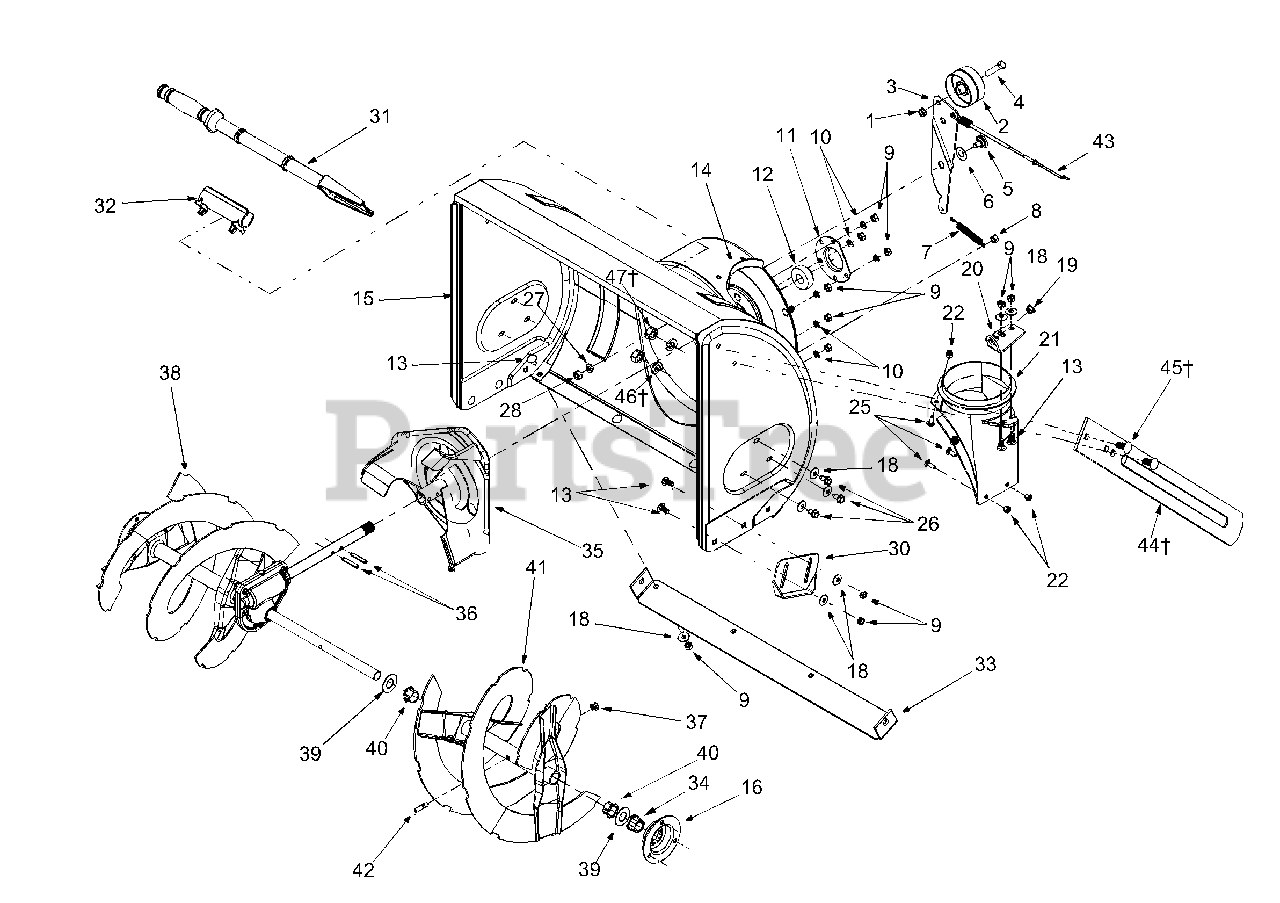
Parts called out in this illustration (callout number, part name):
1	Lock Jam Nut 3/8-24
2	Flat Idler
4	Hex Cap Screw 3/8-24 x 1.50
5	Shoulder Screw
6	Flat Washer,.565 x 1.25 x.02
7	Extension Spring
8	Hex Nut 5/16-18
9	Hex Nut 5/16-18
10	Lock Washer 5/16
11	Housing
12	Ball Bearing
13	Carriage Bolt 5/16-18 x.75
18	Bell Washer
19	Bushing
21	Chute Adapter
22	Hex Flange Lock Nut 1/4-20
25	Carriage Screw 1/4-20 x.75
26	Screw 5/16-12
27	Lock Washer 3/8
28	Hex Nut 3/8-16
31	Chute Clean-out Tool
32	Mount, Chute Clean-out Tool
34	Hex Flange Bearing
37	Lock Nut 5/16-18
39	Flat Washer
40	Flange Bushing
42	Shear Bolt 5/16-18 x 1.5
43	Drive Cable
45	Carriage Bolt 5/16-18
46	Lock Washer 5/16
47	Hex Nut 5/16-18
05139A-0637	BLADE-GUIDE (DRIFT - POWDER BLACK (0637)
05139A-0638	BLADE-GUIDE (DRIFT - MTD/TROY-BILT RED (0638)
05139A-0662	BLADE-GUIDE (DRIFT - OYSTER GRAY (0662)
05139A-0665	BLADE-GUIDE (DRIFT - YARDMAN GREEN (0665)
05139A-0674	BLADE-GUIDE (DRIFT - YARDMAN YELLOW (0674)
05139A-0716	BLADE-GUIDE (DRIFT - CUB YELLOW-99 (0716)
